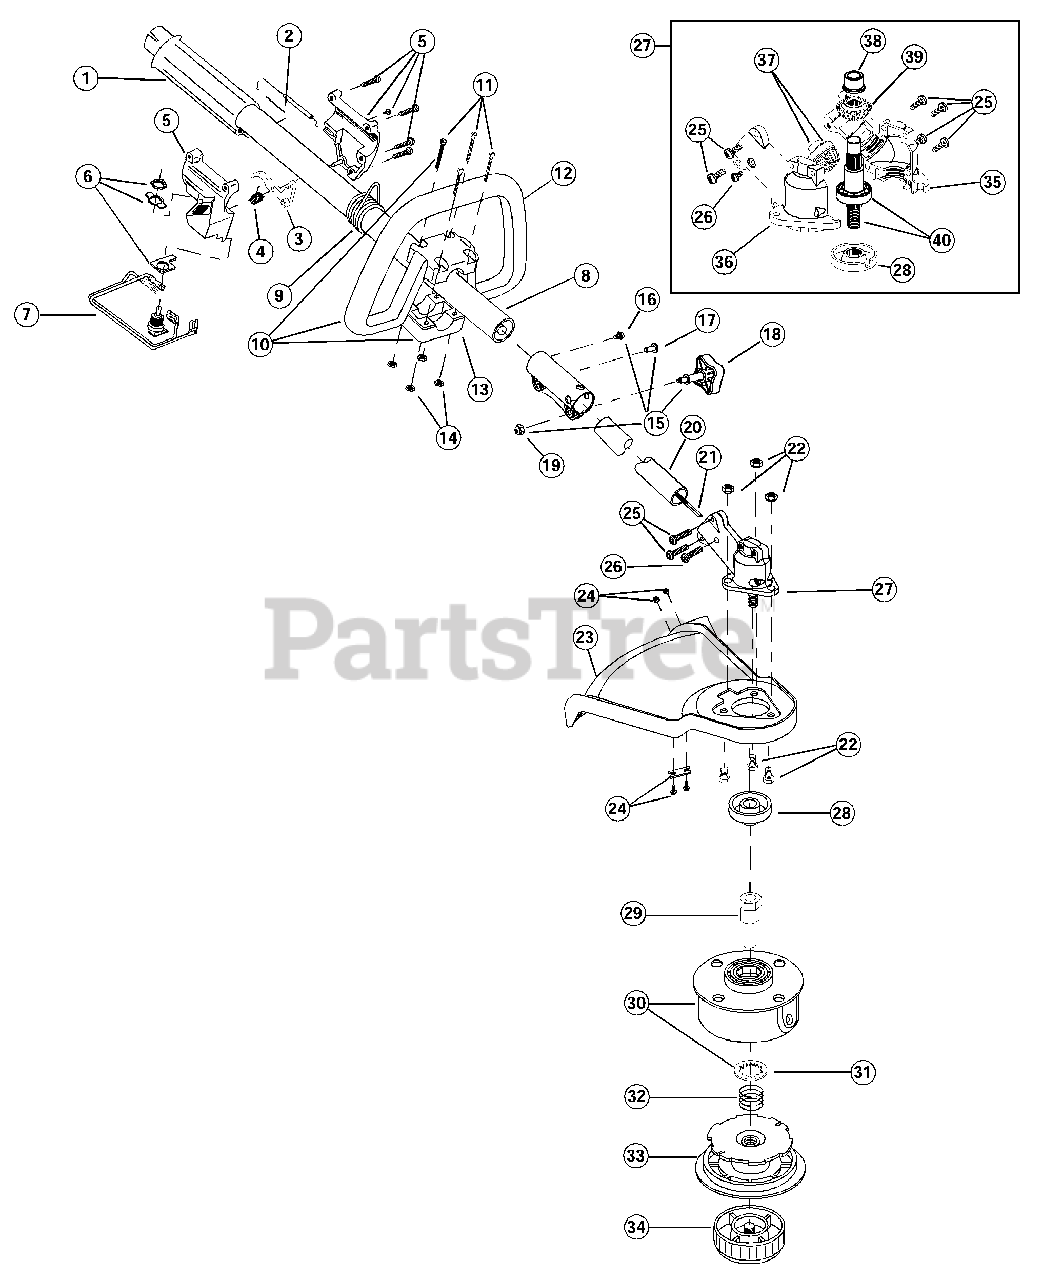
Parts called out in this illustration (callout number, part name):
2	Throttle Cable Assembly
3	Throttle Trigger
4	Throttle Trigger Spring
5	Throttle Trigger Assembly
6	Switch Assembly
7	Wire Lead Assembly
8	Upper Drive Shaft Housing Assembly
9	Shoulder Harness Clamp
10	D-Handle Assembly
12	Loop Handle
13	Bottom Clamp
15	Split Boom Coupler
18	Adjustment Knob
19	Knob Retaining Nut
20	Lower Drive Shaft Housing
21	Drive Shaft
22	Shield Mount Screw Assembly
23	Shield & Blade Assembly
24	Blade Assembly
25	Gearbox Mounting Hardware
26	Anti-Rotation Screw
27	2 piece Gearbox Assembly
28	Blade Driver
29	Spool Shaft
30	Outer Spool & Eyelet Assembly
31	Retainer
32	Spring
33	Inner Reel
34	Bump Head Knob Assembly
35	Left Housing
36	Right Housing
37	Pinion Gear Assembly
38	Output Shaft Bushing
39	Output Shaft Gear
40	Output Shaft Assembly
